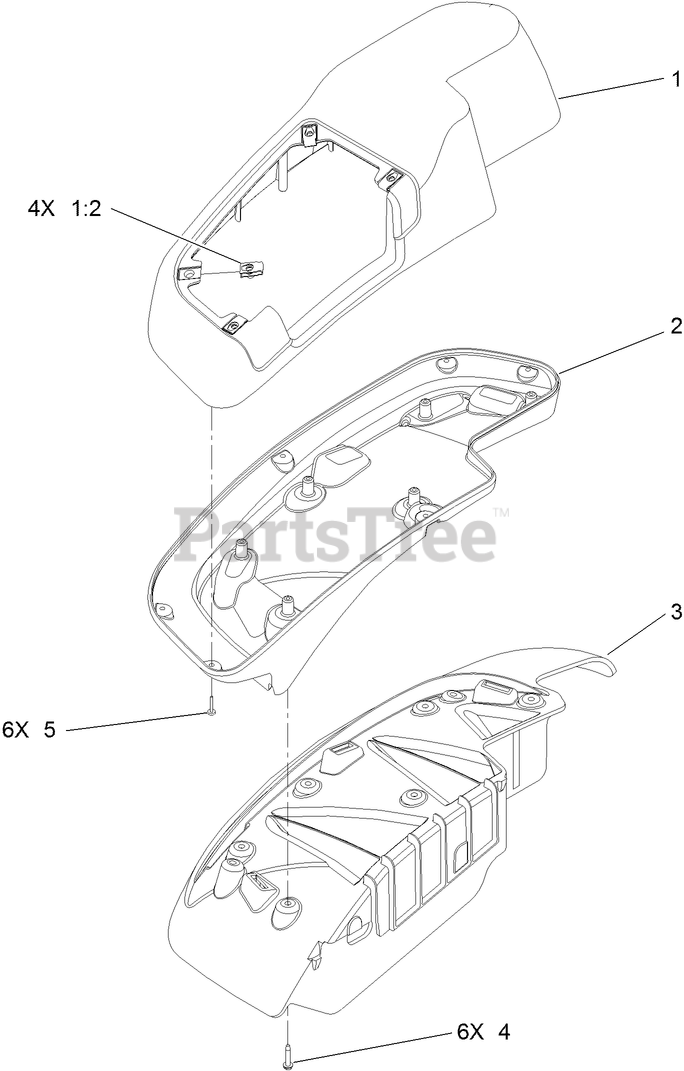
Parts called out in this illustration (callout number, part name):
1	RH CONSOLE TOP ASM
2	CONSOLE-NARROW, RH
3	FENDER-NARROW, RH
4	SCREW-THREAD FORMING
5	SCREW-PPH
